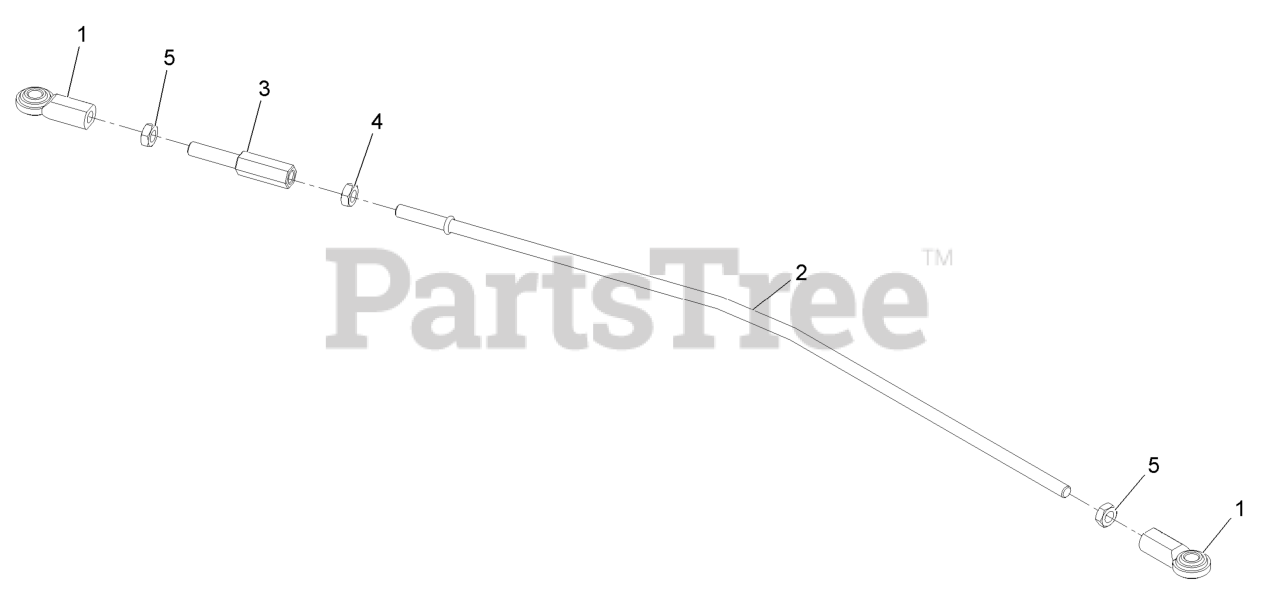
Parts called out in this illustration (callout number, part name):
1	JOINT-BALL, END
2	LINK-LOWER, MOTION CONTRO
3	ROD-ADJUSTMENT
4	NUT-HEX JAM, LH
5	NUT-HJ
